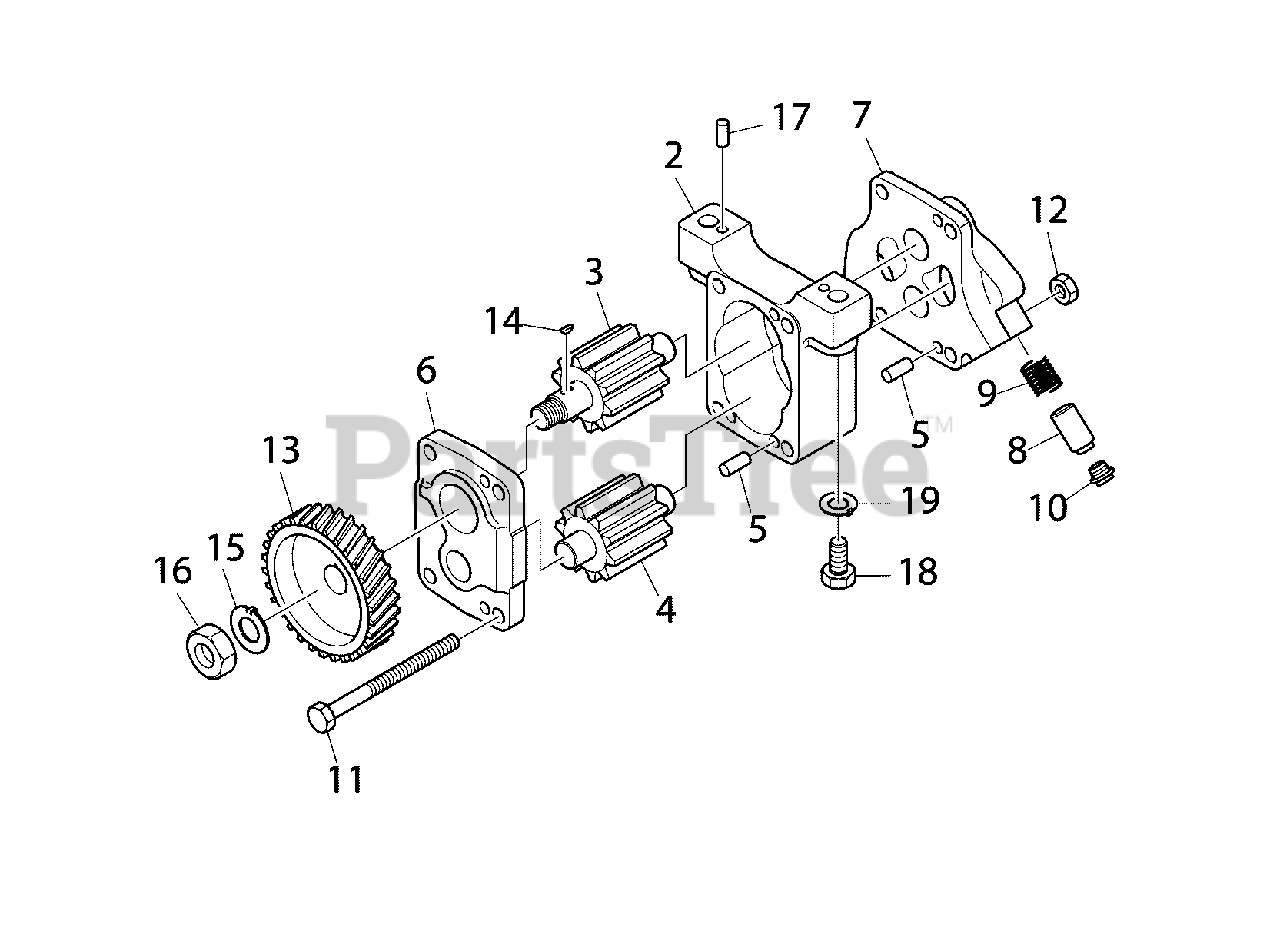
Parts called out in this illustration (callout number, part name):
1	* PUMP, OIL
2	* HOUSING
3	* GEAR, OIL PUMP
4	* GEAR, OIL PUMP
5	* PIN, DOWEL
6	* COVER, OIL PUMP
7	* COVER, OIL PUMP
8	* PLUNGER, VALVE
9	* SPRING, COMPRESS
10	* PLUG, SCREW
11	* BOLT
12	* NUT
13	* GEAR, OIL PUMP DRIVE
14	* KEY, WOODRUFF
15	* WASHER, LOCK
16	* NUT, HEX
17	* PIN, DOWEL
18	* BOLT, HEX
19	* WASHER, LOCK
